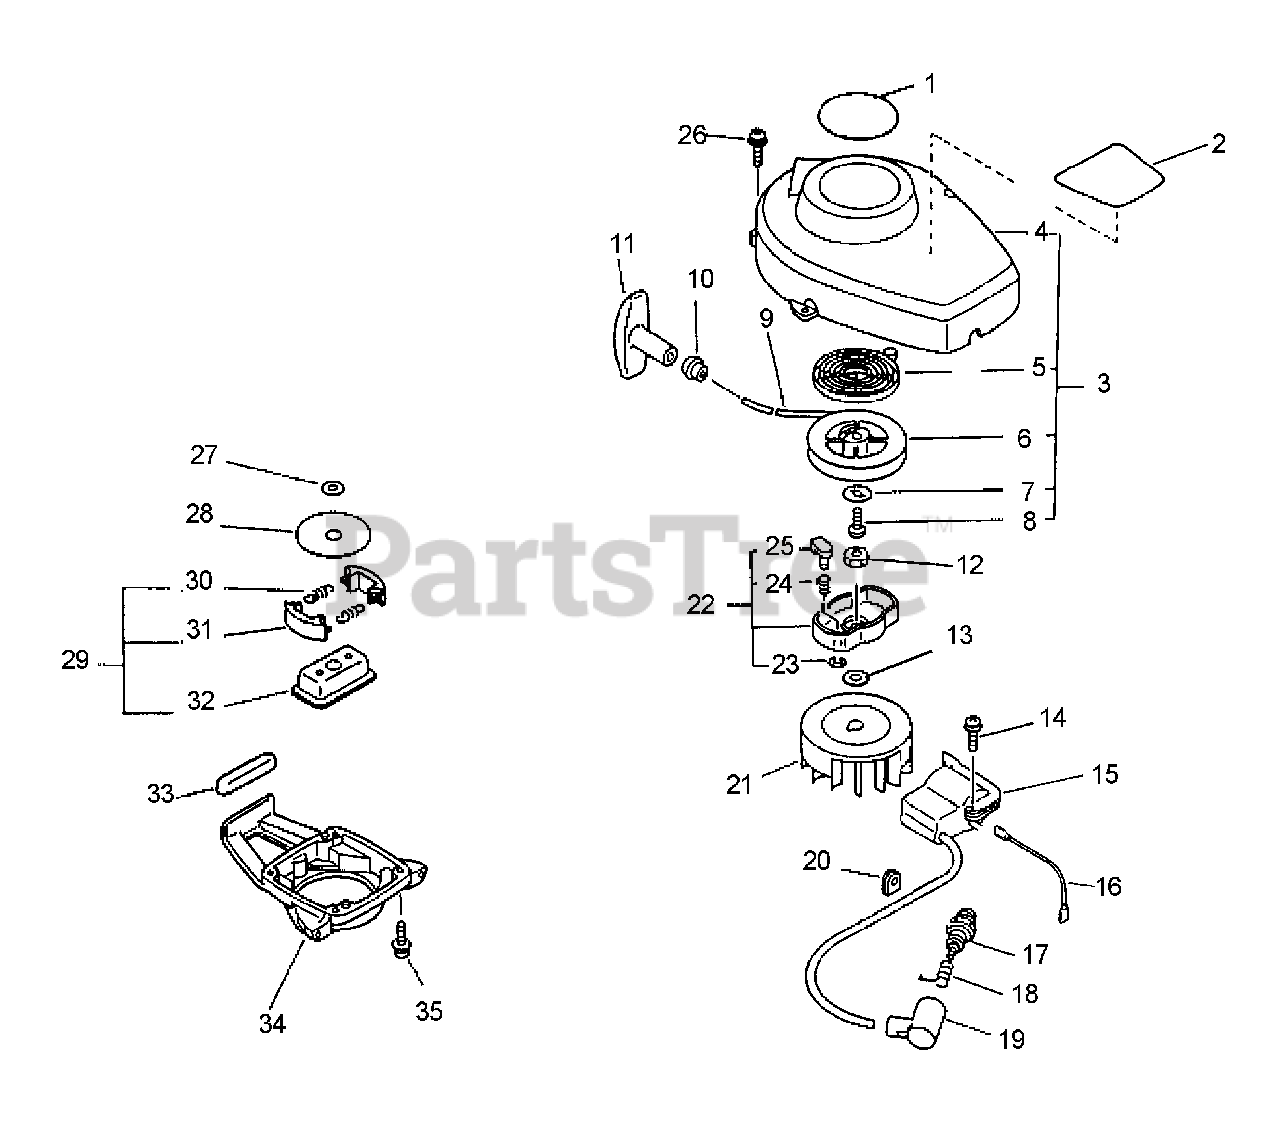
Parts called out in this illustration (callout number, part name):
1	LABEL - ECHO
2	LABEL - MODEL HC-1600
3	STARTER ASSY
4	CASE, STARTER
5	SPRING, REWIND
6	REEL, ROPE
7	WASHER
9	ROPE, STARTER - 3.5X1000
10	GUIDE, ROPE
11	GRIP, STARTER
12	NUT - LEFT HAND
13	LOCKWASHER - 8
14	SCREW - 4X22
15	COIL, IGNITION
16	LEAD - IGNITION
17	SPARK PLUG -- BPM-7A
17	SPARK PLUG -- BPM-7Y
17	SPARK PLUG -- RCJ-7Y
18	TERMINAL, SPARK PLUG CAP
19	CAP, SPARK PLUG
21	FLYWHEEL
22	STARTER PAWL ASSY
23	RING, RETAINING - 4
24	SPRING, RETURN
25	PAWL, STARTER
26	SCREW - 4X16
27	WASHER, CLUTCH
28	PLATE, CLUTCH
29	CLUTCH ASSY
30	SPRING, CLUTCH
31	SHOE, CLUTCH
32	HUB, CLUTCH
33	CUSHION, FUEL TANK
34	CASE, CLUTCH
35	SCREW - 4X16
